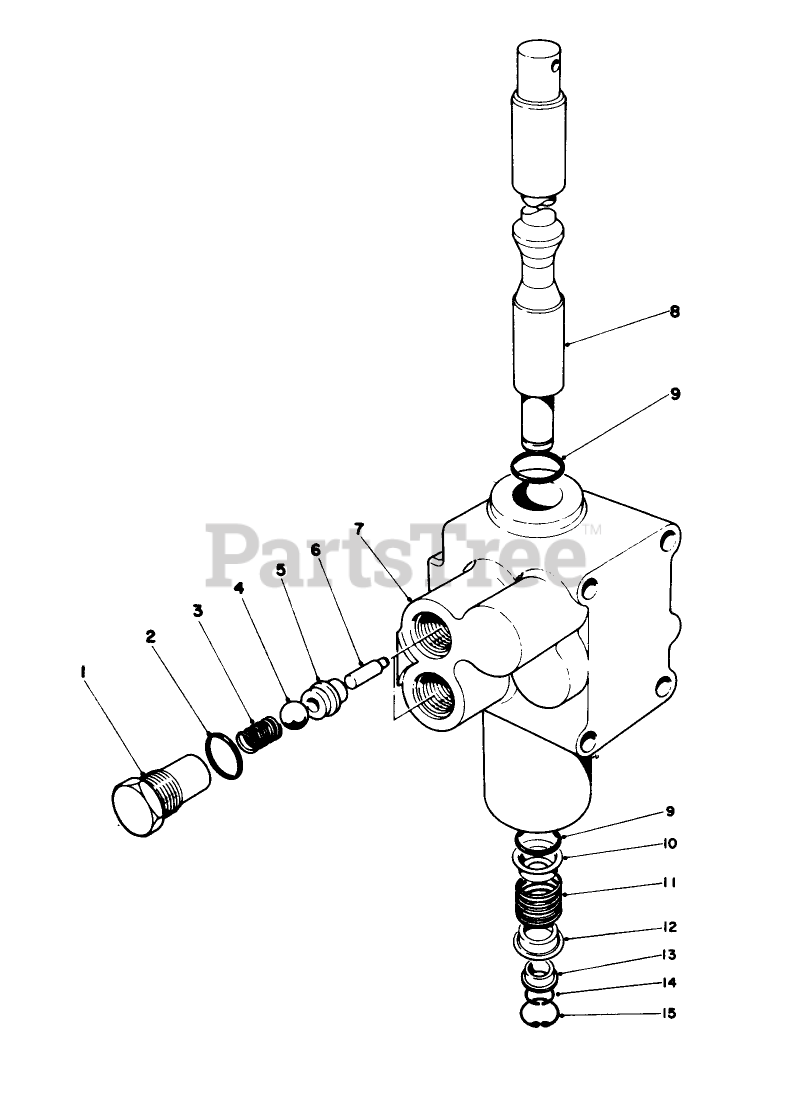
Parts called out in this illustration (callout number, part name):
2	O-RING
3	SPRING
5	SEAT-VALVE
8	SPOOL
9	O-RING
10	RETAINER
11	SPRING
12	RETAINER
13	SPACER
14	RING-SNAP
15	RING-SNAP
